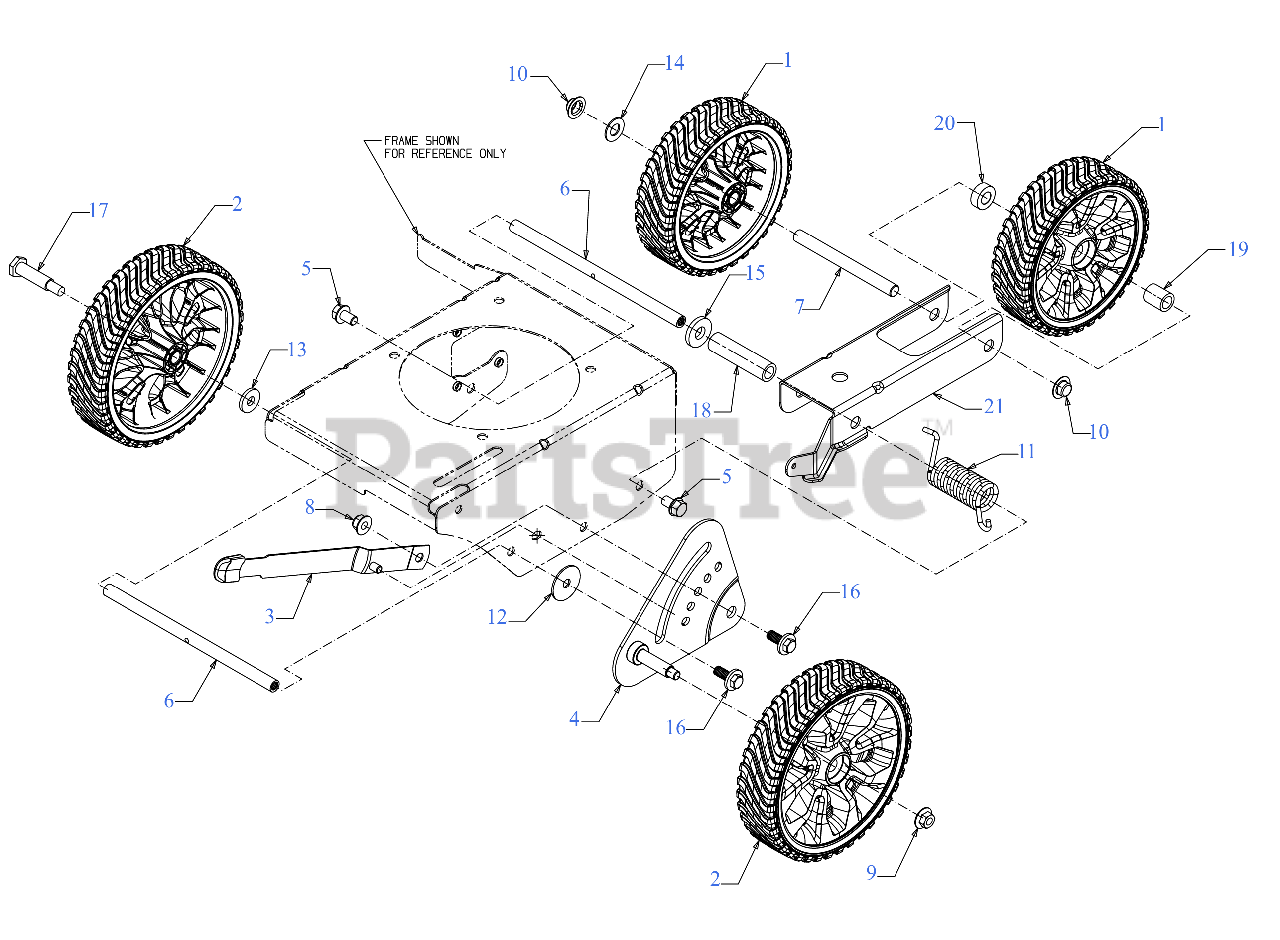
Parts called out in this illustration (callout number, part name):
1	WHEEL ASSEMBLY 7" x 2"
2	WHEEL ASSEMBLY 8 x 2 GRAY
3	WHEEL ADJUSTMENT LEVER ASSEMBLY
4	HEIGHT ADJUST PLATE
5	SCREW 3/8-16X.625 GR 5
6	SPACER .50 x 9.25
9	FLANGE LOCK NUT
11	TORSION SPRING
12	FLAT WASHER .390 ID x 1.50 OD x .075
13	FLAT WASHER .385 x 1.00 x .135
14	FLAT WASHER .510X.995
15	FLAT WASHER .531 x 1.25 x .181
17	SHOULDER BOLT .498 DIA. x 1.64
